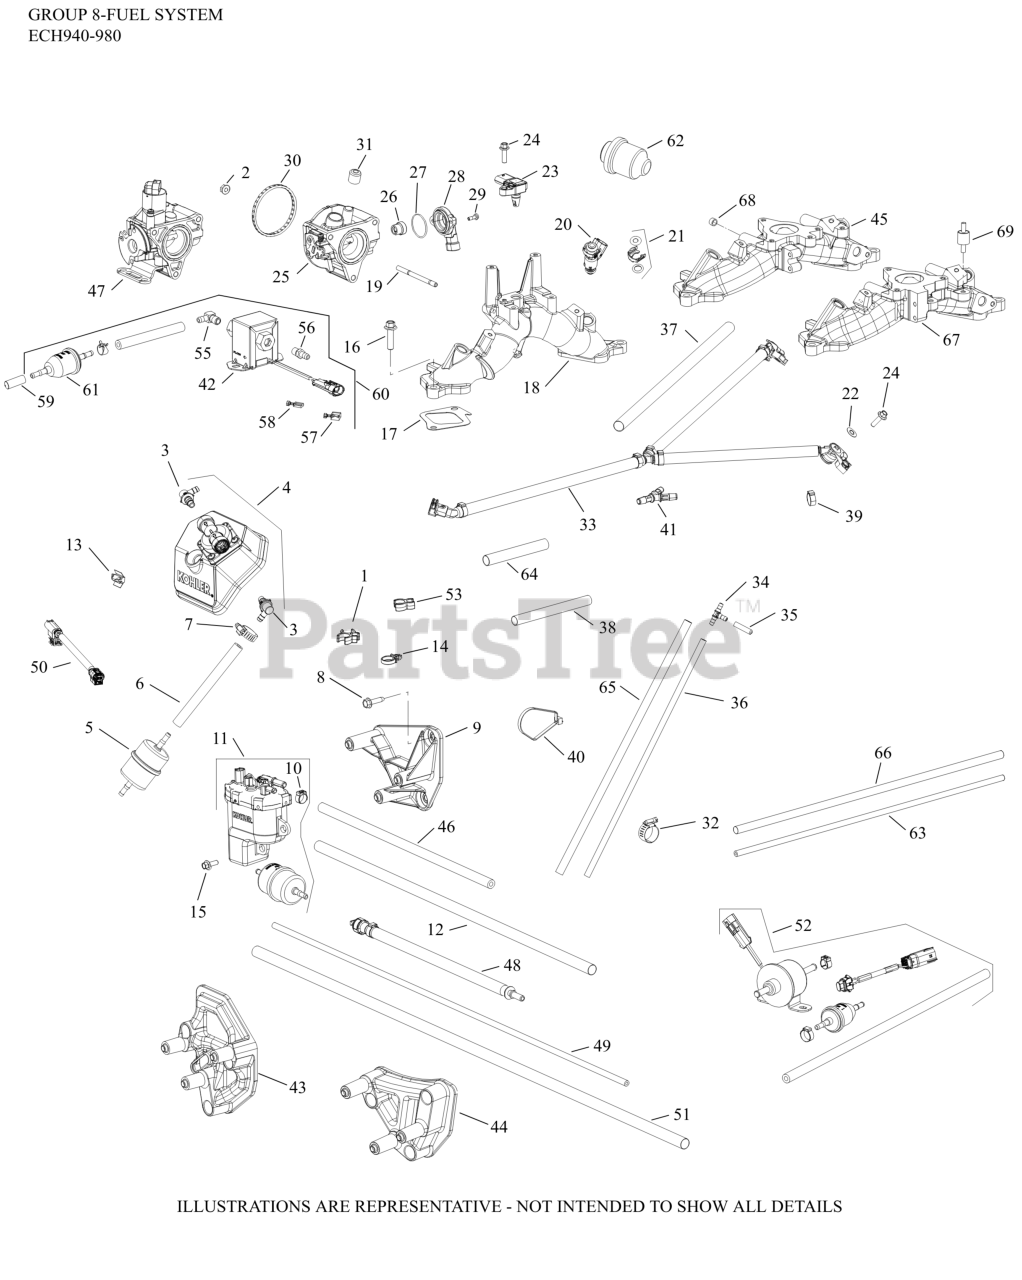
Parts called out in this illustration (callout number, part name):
1	RETAINER, HOSE
2	NUT, FLG M6X1.0
3	KIT, 90 DEG. FITTING
4	KIT, FUEL PUMP
5	FILTER, FUEL
6	HOSE,LW PERM.FUEL 24.00"-USE 25 111 81-S
7	CLAMP, HOSE (KM)-USE 25 237 31-S
8	SCREW, THREAD FORMING
9	BAFFLE, FUEL PUMP MODULE (HORZ)
10	CLAMP, OETIKER
11	KIT,FP MODULE (ECH/ECV 440,630,940)
12	SLEEVE, ANTI ABRASION
13	CLIP, O2 SENSOR
14	CLIP, FUEL LINE
15	SCREW, FLG M6X1.0X16
17	GASKET, INTAKE MANIFOLD
18	MANIFOLD, INTAKE HORIZONTAL (EFI)
19	STUD,M6X1.0X84
20	INJECTOR, FUEL
21	KIT, FUEL INJECTOR O-RING
22	CLIP, RETAINER
23	SENSOR, T-MAP
24	SCREW, FLG M6x1.0x20
25	BODY, THROTTLE ASM (34)
26	MAGNET ASSEMBLY, TPS
27	O-RING, TPS SENSOR
28	SENSOR, THROTTLE POSITION
30	O-RING (HDAC SEAL-EFI)
31	CAP, MASKING
33	RAIL ASSEMBLY, FUEL (HORZ)
34	TEE CONNECTOR
35	CAP, MASKING
36	HOSE, EVAPORATIVE
37	SLEEVE, ANTI ABRASION
38	SLEEVE, ANTI ABRASION -USE 25 431 12-S
39	CLAMP, HOSE
